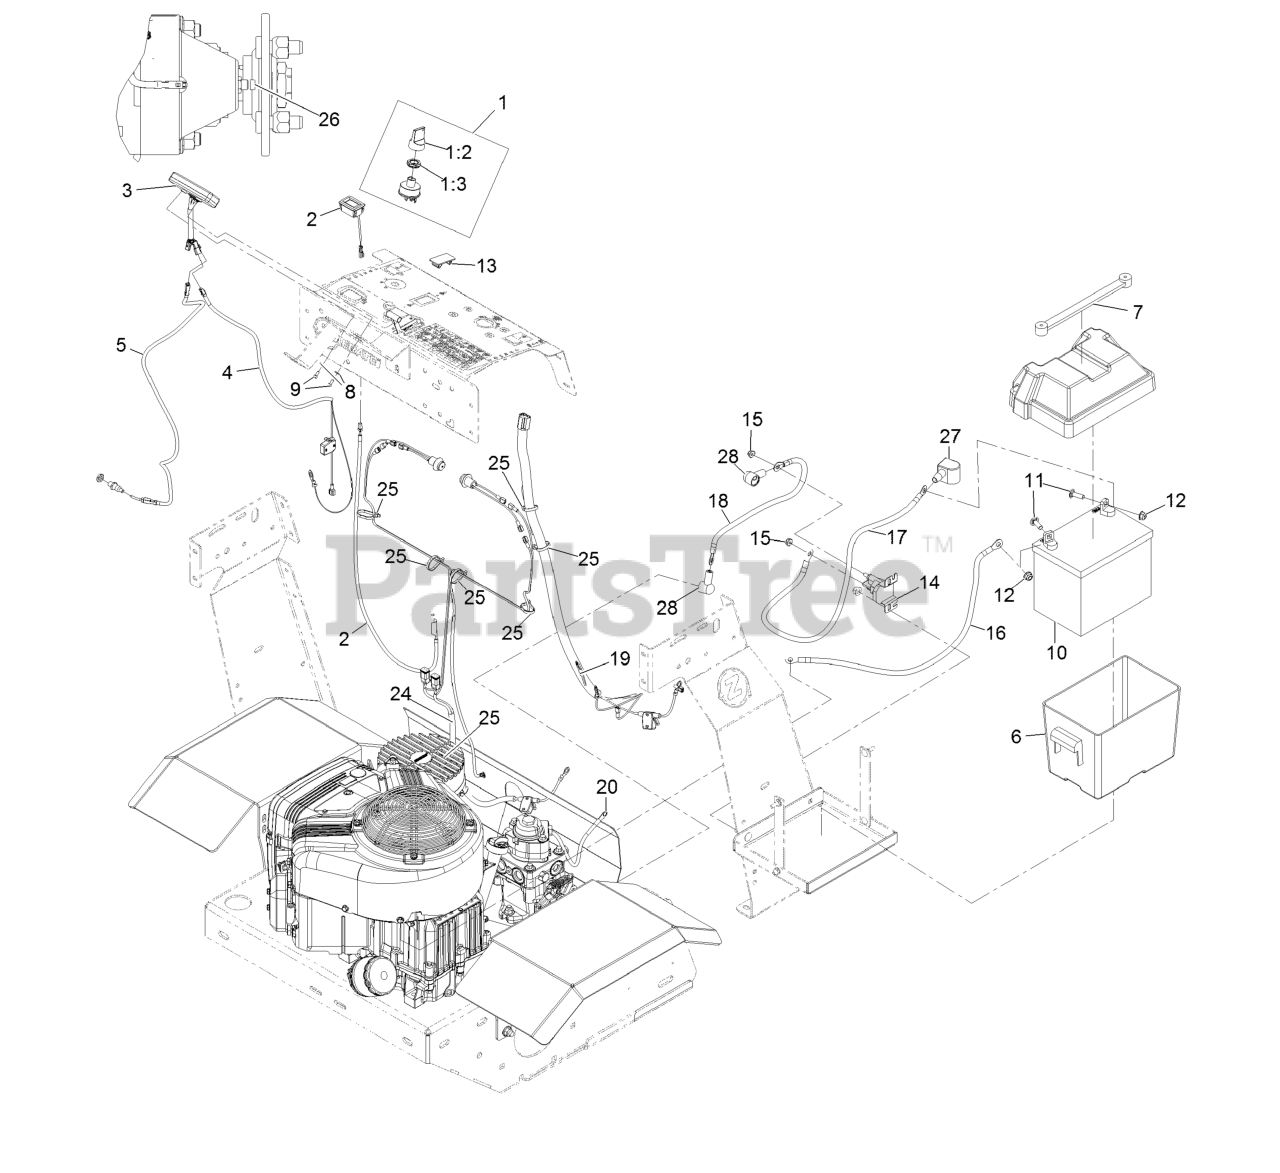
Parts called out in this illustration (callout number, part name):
1	ASM-SWITCH, KEY
1:2	KEY-UMBRELLA
1:3	NUT-SWITCH, KEY
2	METER-TACH/HOUR
3	HEAD ONLY, STRIKER
4	HARNESS-STRIKER
5	Cable-Trail Tech, Sensor
6	BATTERY BOX ASM
7	BUNGEE (TARP STRAP)
8	WASHER-FLAT
9	SCREW-HSH
10	Battery (340 CCA, Wet)
11	SCREW-CARR
12	NUT-HF, NI
13	PLUG-HOLE
14	Solenoid-Starter
16	CABLE-GROUND
17	28" RED BATTERY CABLE
18	CABLE-POSITIVE
19	WIRING HARNESS
20	WIRE-SOLENOID
24	HARNESS, KIT, THUMB SWITCH, ZP
25	TIE-CABLE
26	MAGNET, SPEEDOMETER
27	Insulator-Battery
28	INSULATOR-SOLENOID
